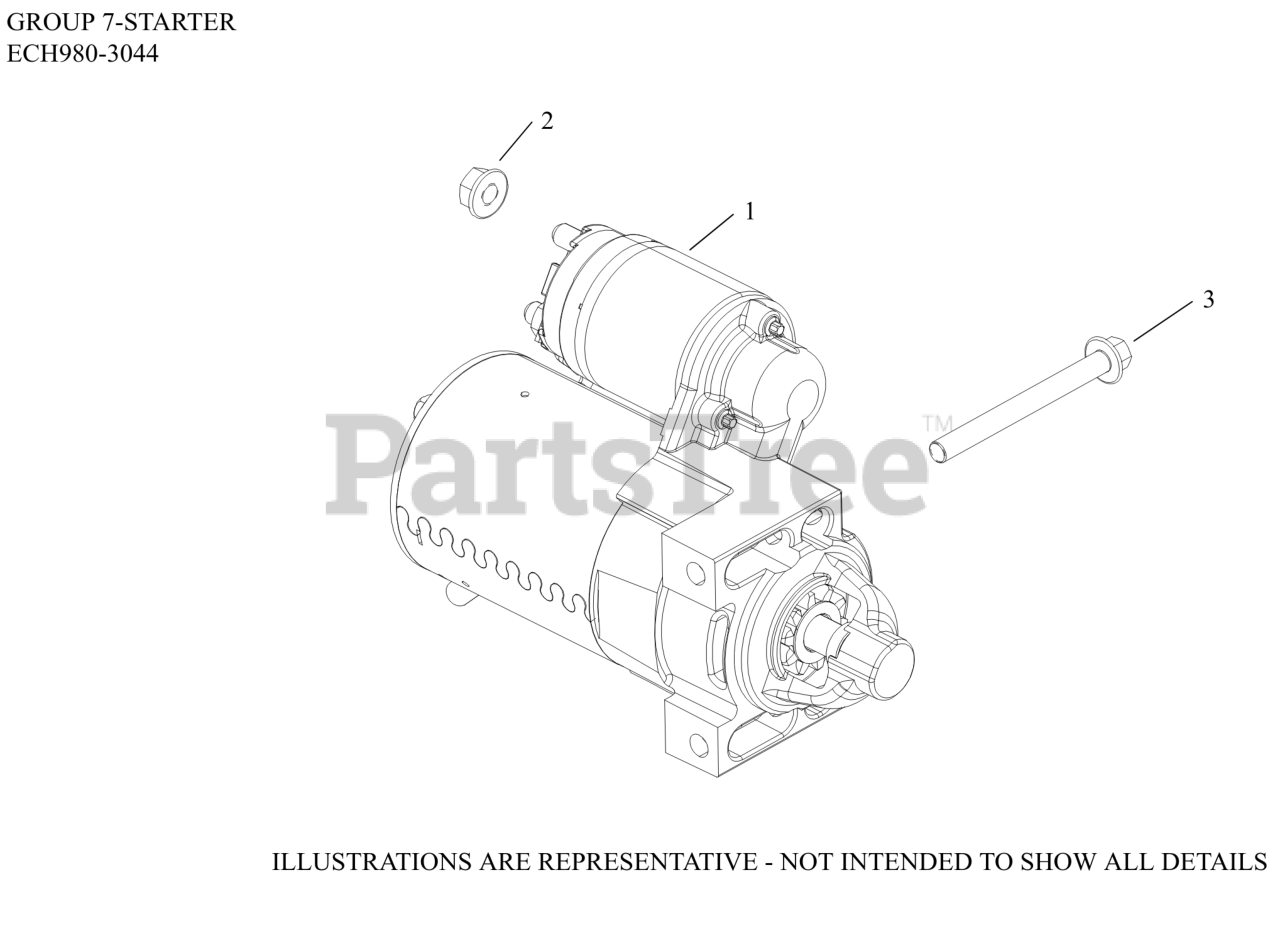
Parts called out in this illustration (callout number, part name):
1	STARTER, SOLENOID SHIFT
2	NUT, FLG M8X1.25
3	SCREW, FLG M8X1.25X80
